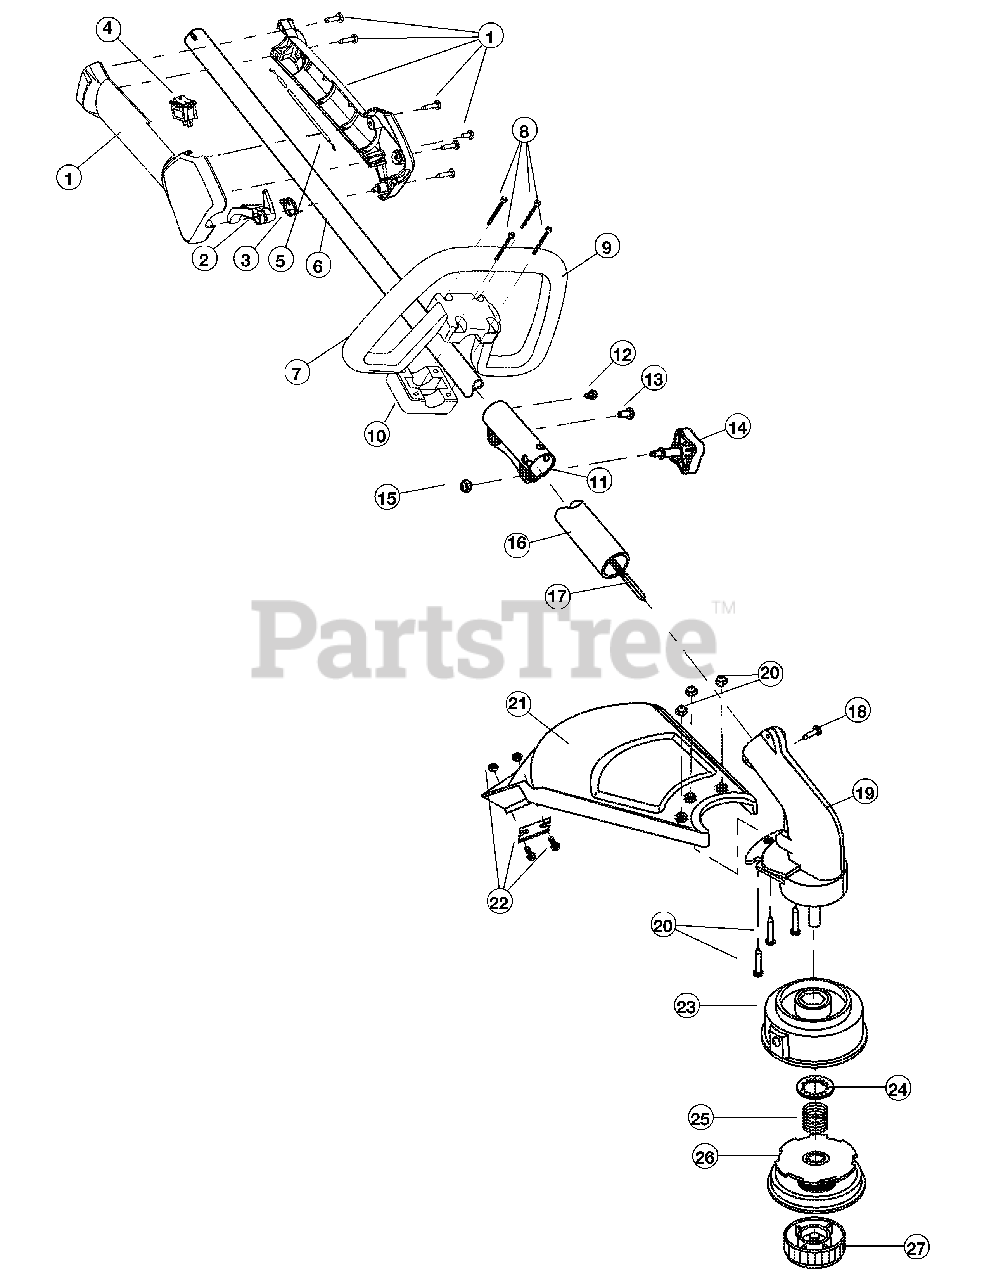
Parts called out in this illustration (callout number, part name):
1	Throttle Housing Assembly (includes 2-4)
2	Throttle Trigger
3	Throttle Trigger Spring
5	Throttle Cable Assembly
6	Upper Drive Shaft Housing Assembly
7	Deluxe D-Handle Assembly (includes 8-10)
9	Deluxe D-Handle
10	Bottom Clamp
11	Split Boom Coupler (includes 12-15)
14	Adjustment Knob
15	Knob Retaining Nut
16	Lower Drive Shaft Housing Assembly
17	Lower Flexible Drive Shaft
18	Anti-Rotation Screw
19	Gear Box Assembly (includes 23-27)
20	Shield Mounting Hardware
21	Shield Assembly (includes 22)
22	Blade Assembly
23	Outer Spool Assembly (includes 24)
24	Retainer
26	Inner Reel
27	Bump Head Knob Assembly
